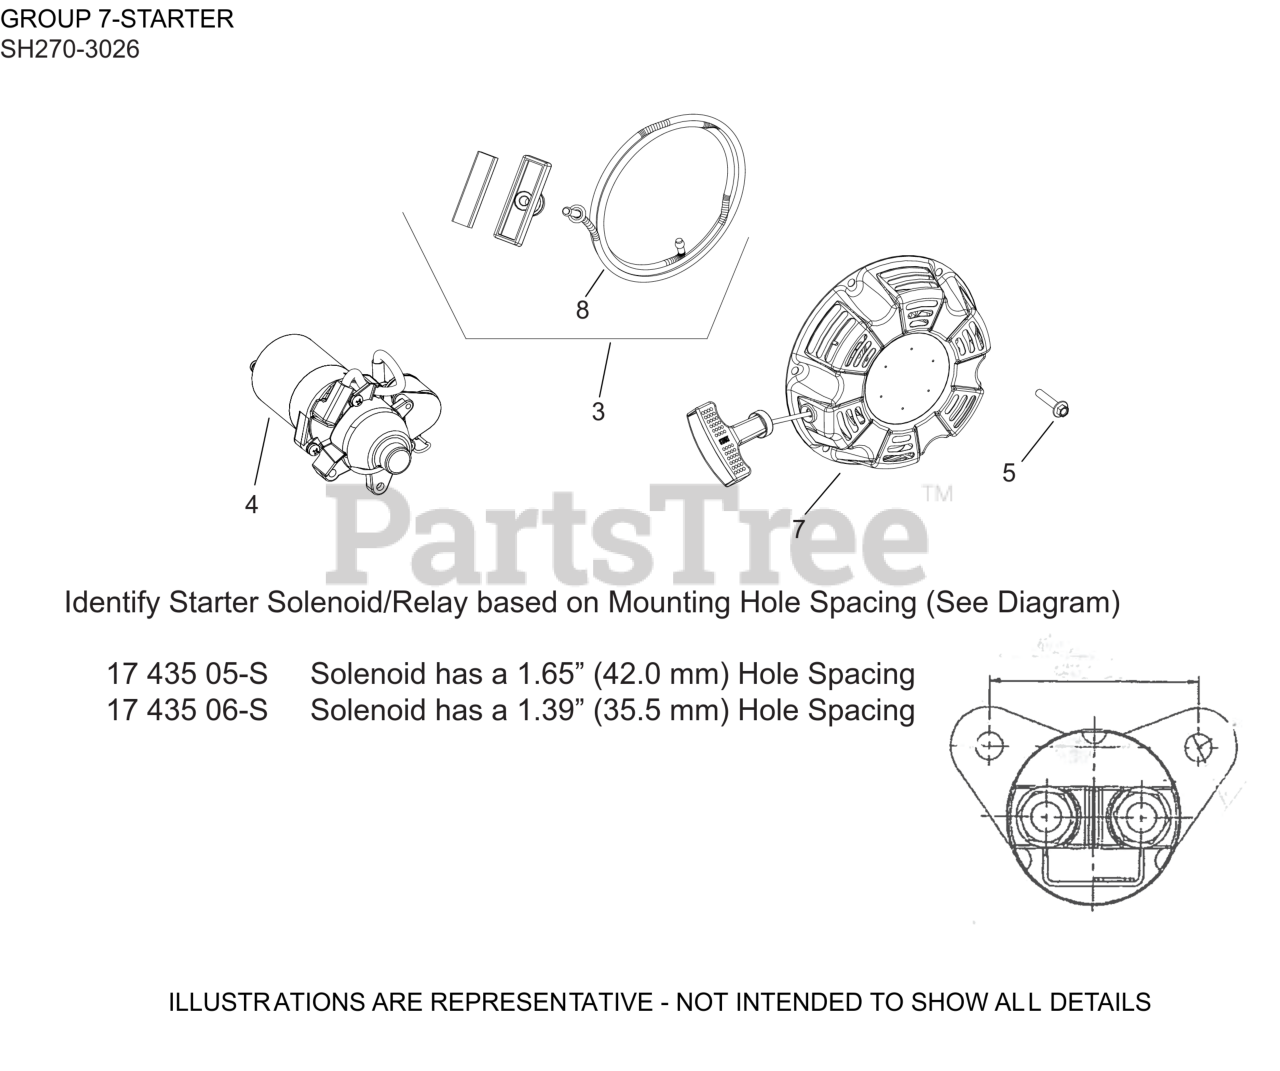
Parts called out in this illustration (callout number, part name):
3	KIT, STARTER ROPE W/HANDLE
4	ELECTRIC STARTER-BENDIX DRIVE
5	SCREW, STARTER MOUNTING
7	RETRACTABLE STARTER ASSEMBLY
8	ROPE, STARTING
